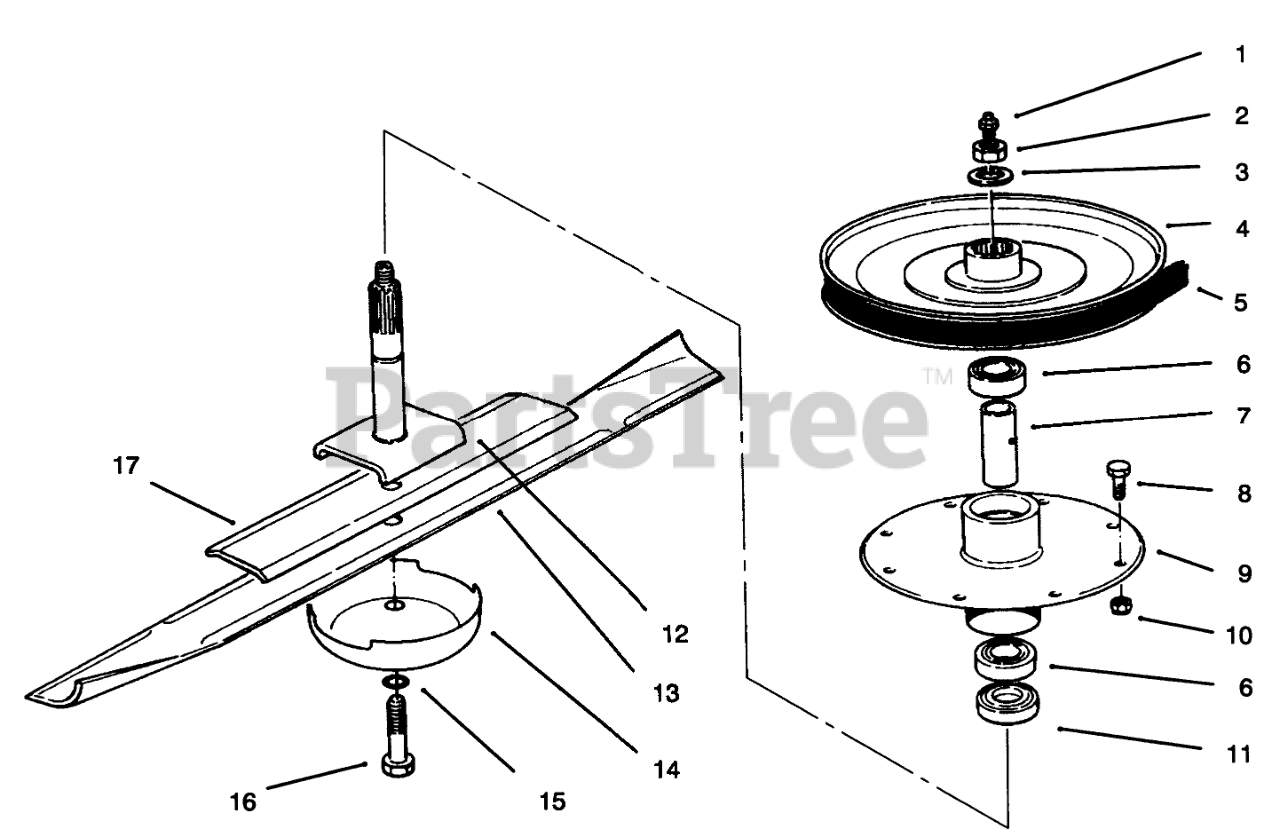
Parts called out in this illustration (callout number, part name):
1	FITTING-GREASE
2	NUT-HEX
3	WASHER
4	PULLEY ASM
5	V-BELT
6	BEARING-BALL
7	SPACER-BEARING
8	SCREW-HH
9	HOUSING-SPINDLE
10	NUT-LOCK, NI
11	SPACER
12	SHAFT-SPINDLE
13	BLADE-RECYCLER
14	CUP-SCALP, ANTI
15	WASHER-LOCK/SP
16	SCREW-BLADE
17	BLADE SPACER ASSEMBLY
